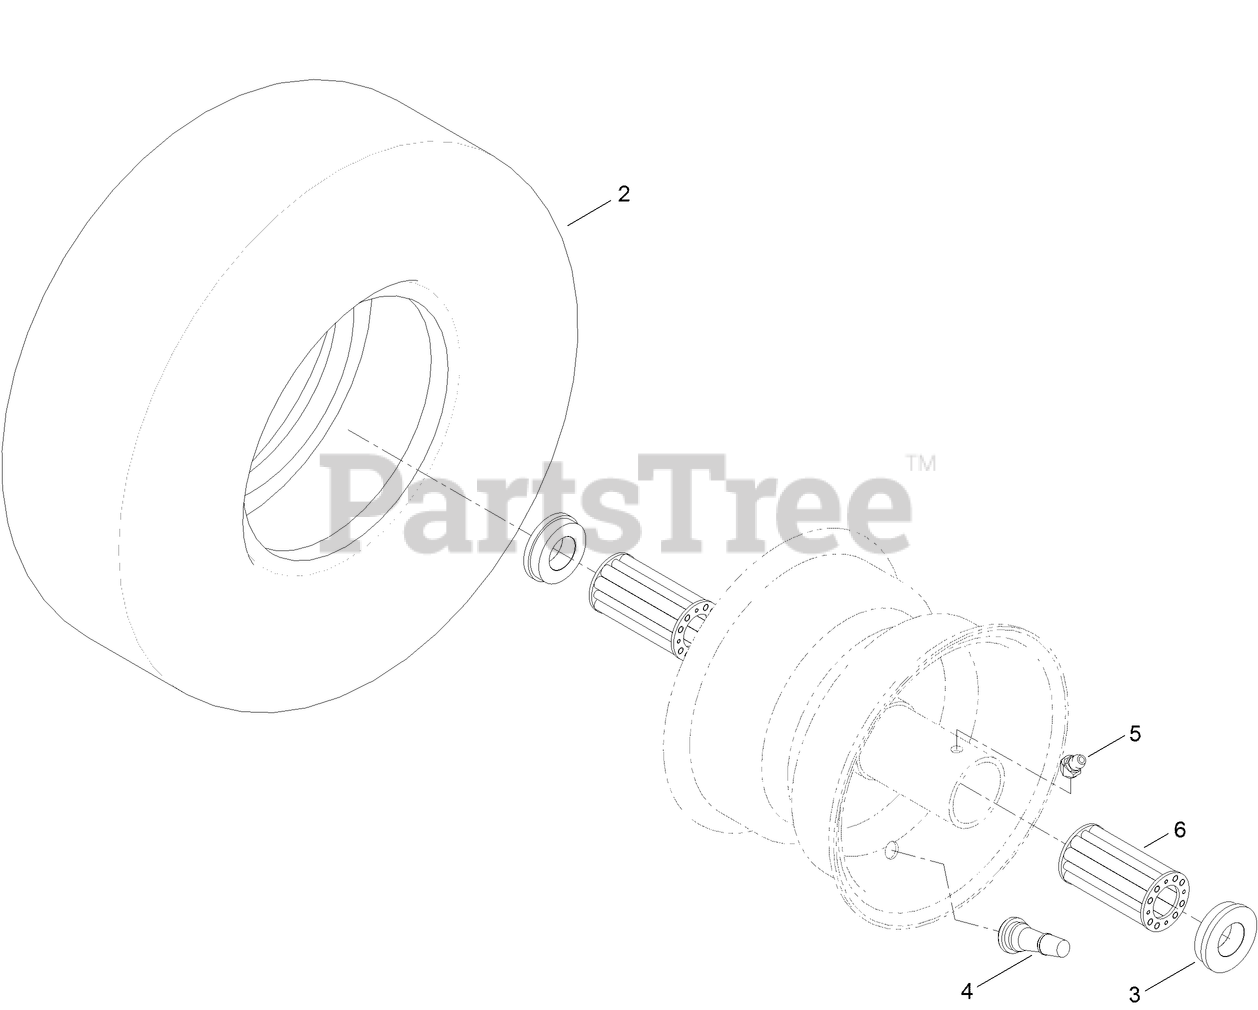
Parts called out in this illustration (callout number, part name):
3	BUSHING-FLANGE
4	VALVE
5	FITTING-ZERK
6	BEARING
99	TUBE-INNER
